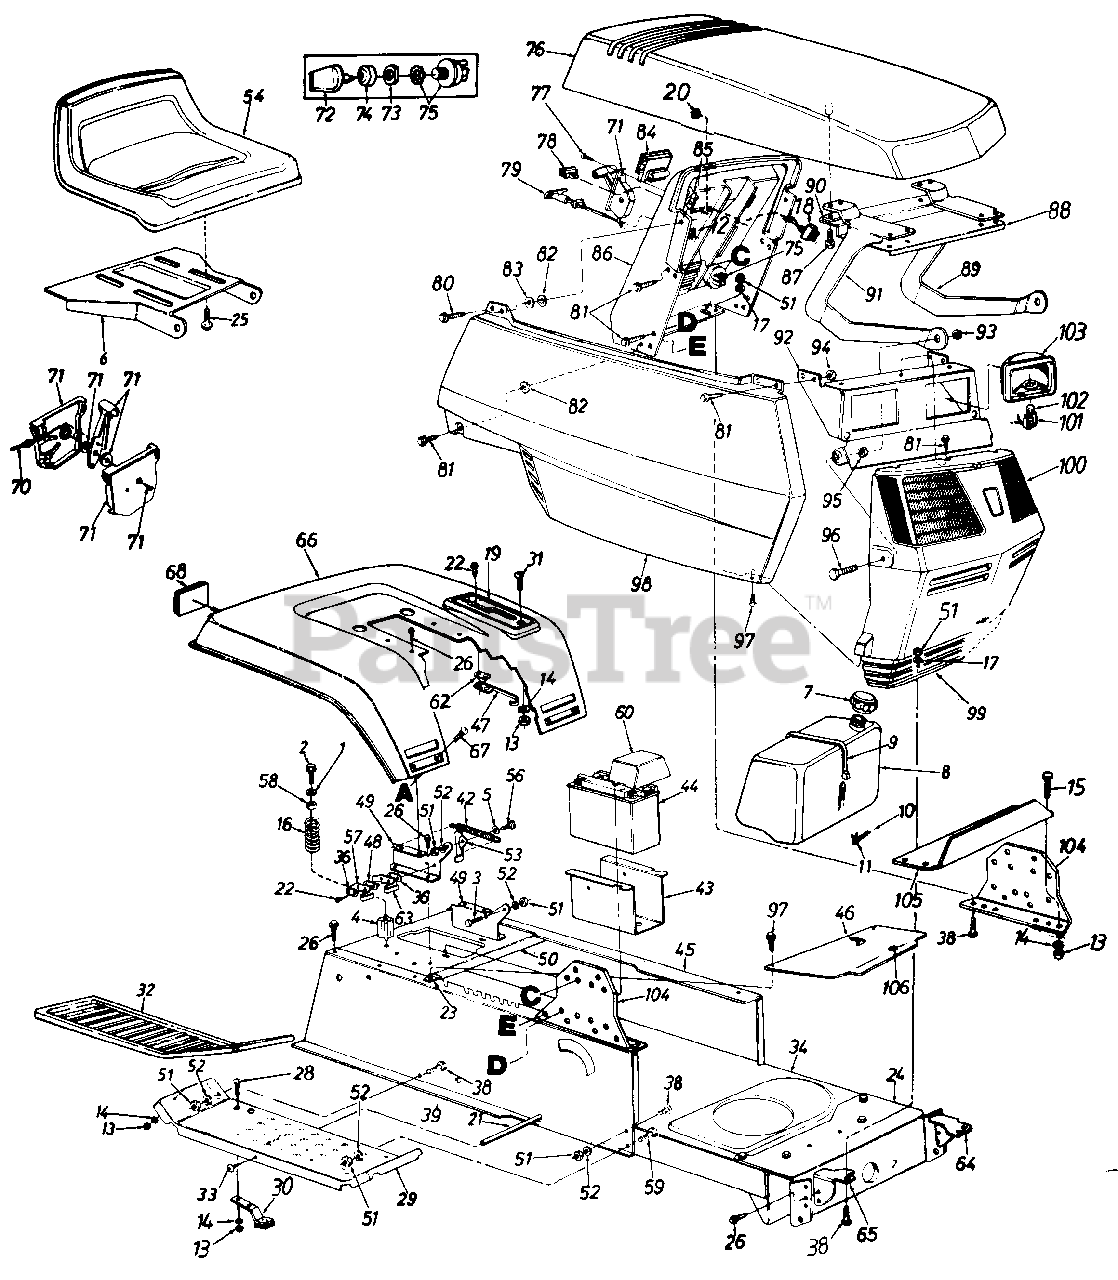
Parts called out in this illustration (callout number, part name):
1	Fl-Wash. .344" I.D. x .875"
2	Hex Wash. Hd. Tap Scr. 5/16-18 x 3.25" Lg.
3	Shld. Bolt .437" Dia. x .162"
4	Spring Spacer
5	Spr-Wash. .445" I.D. x .75
6	Seat Pivot Bracket
7	Fuel Cap w/o Gasket
8	Fuel Tank
9	Tie Strap
10	Fuel Line
11	Hose Clamp
12	Choke Retainer
13	Hex Nut 1/4-20 Thd.
14	L-Wash. 1/4" I.D.
15	Hex Bolt 1/4-20 x .62" Lg.
16	Compression Spring
17	Fl-Wash. .34" I.D. x .68"
18	Toggle Switch
19	Speed Control Index Brkt.
20	Hex Nut 1/2-27 Thd.
21	Running Board Rod
22	Hex Wash. Hd. AB-Tap Scr. #8 x .50" Lg.
23	Speed Nut #10Z
24	Front Pivot Brkt.
25	Hex Tap Scr. 3/8-16 x .75"
26	Hex Wash. Hd. AB-Tap Scr. 5/16 x .75" Lg.
28	Carriage Bolt 1/4-20 x .62"
29	Running Board
30	Blade Brake Ass'y.
31	Truss Mach. Scr. 1/4-20 x .75"
32	Rubber Foot Pad L.H.
33	Truss Mach. Scr. 5/16-18 x .75" Lg.
34	Lower Frame
36	Insulator Plate
38	Hex Bolt 5/16-18 x .75" Lg.
39	Upper Frame R.H.
42	Extension Spring 5.31" Lg.
43	Battery Tray
44	12-V Battery (275 Cold Crank Amps)
45	Upper Frame L.H.
46	Shift Cover
47	Reverse Safety Switch
48	Insulator Boss Plate
52	L-Wash. 5/16" I.D.
53	Seat Lift Brkt.
54	Seat
56	Shld. Bolt .437" Dia. x .268"
57	Spring Switch
58	Bushing
59	Hex Wash. Hd. Scr. 5/16-18 x .87" Lg.
60	Battery Cover
62	Insulator Nut Plate
63	Safety Switch (Seat)
64	Grille Mount Brkt. L.H.
65	Grille Mount Brkt. R.H.
68	Reflector
70	Throttle Wire .35" Lg.
71	Throttle Control Box Ass'y.
72	Ignition Key
73	Ignition Switch Nut
74	Ignition Switch Cap
75	Ignition Switch
78	Light Switch
79	Choke Control 29" Lg.
80	Hex Wash. Hd. Tap Scr. 1/4 x .75" Lg.
81	Hex Tap Scr. 1/4-20 x .5" Lg.
82	Push Nut Fastener
83	Fl-Wash. .27" I.D. x .948"
84	Ammeter
85	Speed Nut 1/4-20 Thd.
86	Dash Panel
87	Hex Wash. Hd. B-Tap Scr. 1/4 x .62" Lg.
88	Hood Reinforcement
89	Hood Hinge L.H.
94	Hex L-Nut 1/4-20 Thd.
95	Hex Jam Nut 5/16-18 Thd.
96	Hex Bolt 5/16-18 x 7/8" Lg.
97	Truss Mach. B-Tap Scr. #10 x .5" Lg.
98	Side Cover R.H.
99	Grille
100	Lens L.H.
101	Twist Lock Lamp Socket
102	Lamp
103	Headlight Housing
106	Snap Bushing
